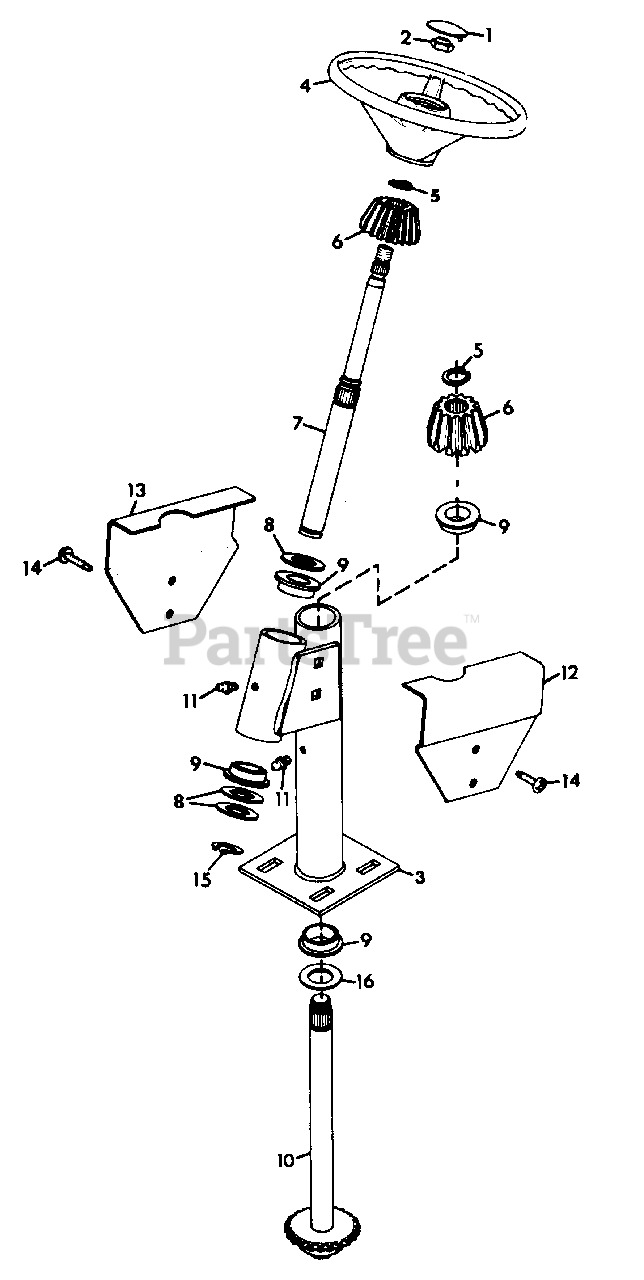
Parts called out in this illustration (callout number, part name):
1	CAP, STEERING WHEEL
2	NUT, JAM 5/8-11
3	TUBE, STEERING
4	WHEEL, STEERING
5	RING, RETAINING
6	PINION, BEVEL
7	SHAFT, STEERING WHEEL
8	RACE, BEARING THRUST
9	BEARING, FLANGED
10	SHAFT, STEERING
11	FITTING, LUBE 1/4-28
12	GUARD, STEERING L.H.
13	GUARD, STEERING R.H.
14	SCREW, TAPPING 10-24X.50
15	RING, RETAINING
16	RACE, BEARING THRUST .030
